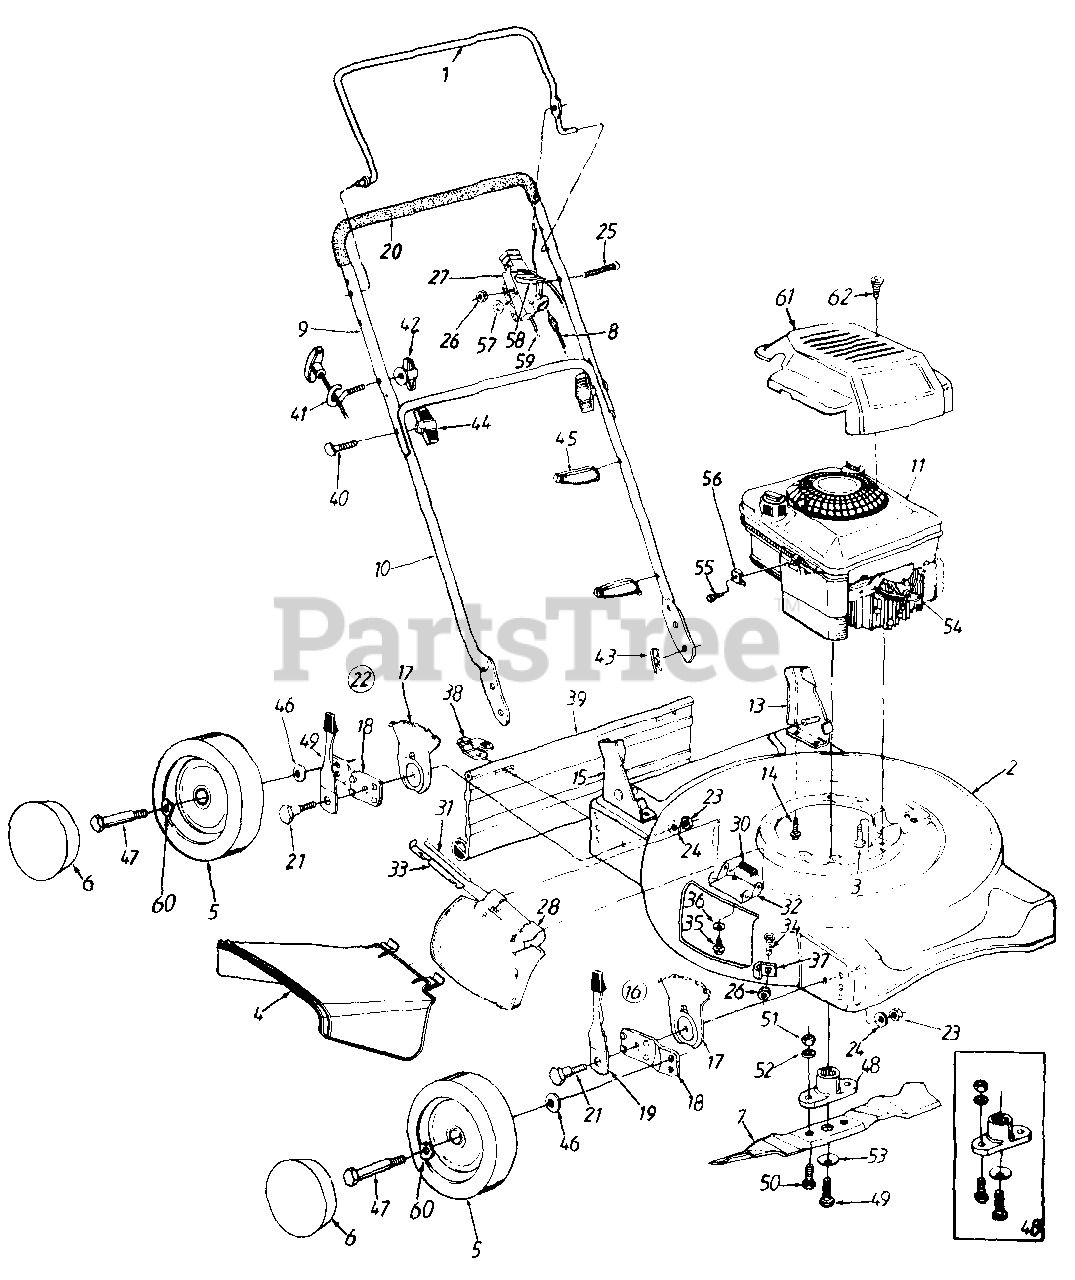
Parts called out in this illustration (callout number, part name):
1	Control Handle
2	20" Deck Assembly
3	Hex TT-Tap Scr. 3/8-16 x 1" Lg.
4	Side Chute Deflector
5	Wheel Ass'y. Comp.
6	Hub Cap
7	20" Mulching Blade
8	Control Cable - 39" (Green)
11	5 H.P. Engine
17	Height Adj. Plate
19	Spring Lever Ass'y. w/Knob
20	Foam Grip
21	Shoulder Bolt .5" Dia. x .434"
22	Height Adj. Ass'y. - L.H.
23	Hex Nut 3/8-16 Thd.
24	Bell-Wash. .39" I.D.
25	Oval C-Sunk Mach. Scr.
26	Hex L-Nut 1/4-20 Thd.
27	Throttle Body
28	Mulching Plug Ass'y.
30	Torsion Spring
31	Hinge Pin
34	Carriage Bolt 1/4-20 x .5" Lg.
35	Hex TT-Tap Scr. 1/4-20 x .5" Lg.
36	Bell-Wash. .265" I.D.
40	Carriage Bolt 5/16-18 x 2" Lg.
42	Wing Nut 1/4-20 Thd.
43	Int. Cot-Pin 5/16" Dia.
44	Handle Knob
45	Cable Tie
46	Bell-Wash. .38" I.D. x .88" O.D.
48	Blade Adapter Kit
49	Hex Bolt 3/8-24 x 1.5" Lg. - Gr. 5
50	Hex Bolt 3/8-24 x 1" Lg.
51	Hex Nut 3/8-24 Thd.
52	L-Wash. 3/8" I.D.
53	Bell-Wash. .39" I.D.
54	Spark Plug Boot
55	Hex Self-Tap Scr. #10-32 x .62" Lg.
56	Cable Clamp
57	Spr. Wash. .66" I.D.
58	Throttle Lever
59	Throttle Wire - 51" (Red)
60	Wave-Wash.
61	Engine Shroud
62	Screw #10 x 1.25" Lg.
